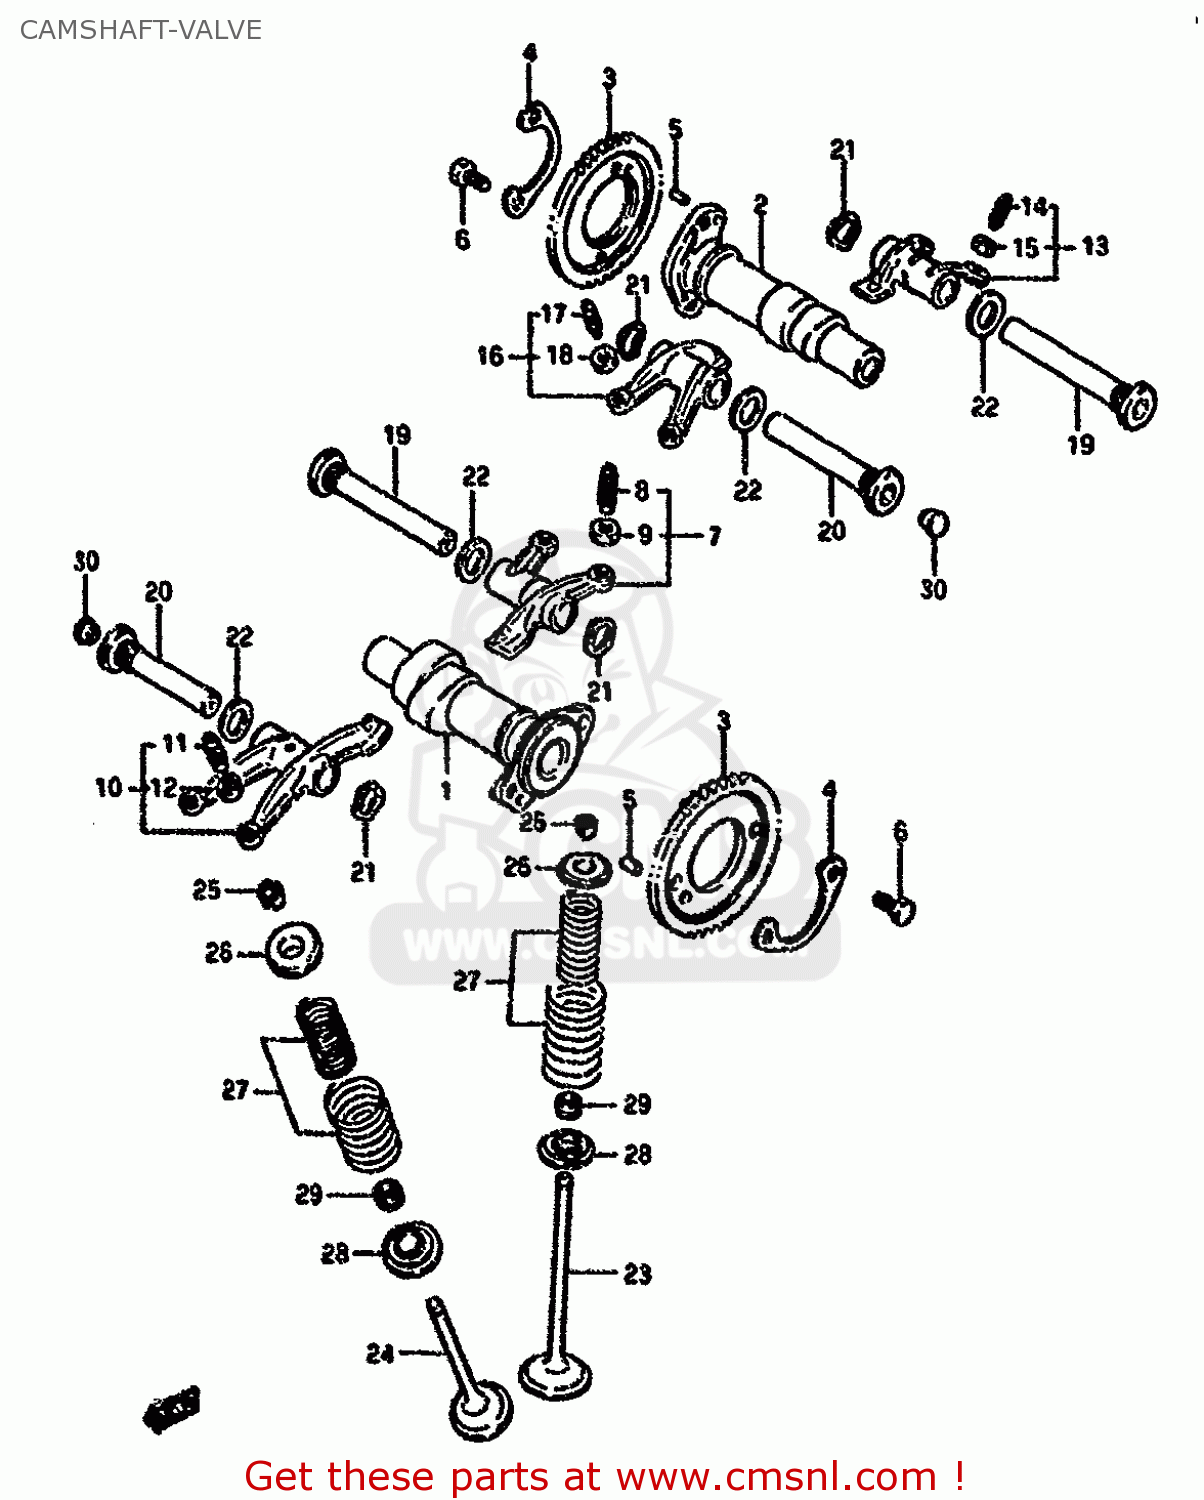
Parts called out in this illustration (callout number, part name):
1	CAMSHAFT,FRONT
2	CAMSHAFT,RR
3	SPROCKET,CAMSHAFT(NT:42)
4	WASHER,CAM CHAIN SPROCKET
5	PIN
6	BOLT(6X12.5)
7	ARM,INTAKE VALVE ROCKER FR
8	SCREW,TAPPET ADJUSTING
9	NUT,ADJUSTING SCREW
10	ARM,EXHAUST VALVE ROCKER FR
11	SCREW,TAPPET ADJUSTING
12	NUT,ADJUSTING SCREW
13	ARM,INTAKE VALVE ROCKER RR
14	SCREW,TAPPET ADJUSTING
15	NUT,ADJUSTING SCREW
16	ARM,EXHAUST VALVE ROCKER RR
17	SCREW,TAPPET ADJUSTING
18	NUT,ADJUSTING SCREW
19	SHAFT,INTAKE VALVE ROCKER ARM
20	SHAFT,EXHAUST VALVE ROCKER ARM
21	WASHER
22	GASKET(13.8X18.8X4.8) (NAS)
23	VALVE,INTAKE
24	VALVE,EXHAUST
25	COTTER,VALVE
26	RETAINER,VALVE SPRING
27	SPRING SET,VALVE
28	SEAT,VALVE SPRING
29	SEAL,OIL(5.5X11X8.2)
30	CAP(OD:12)
